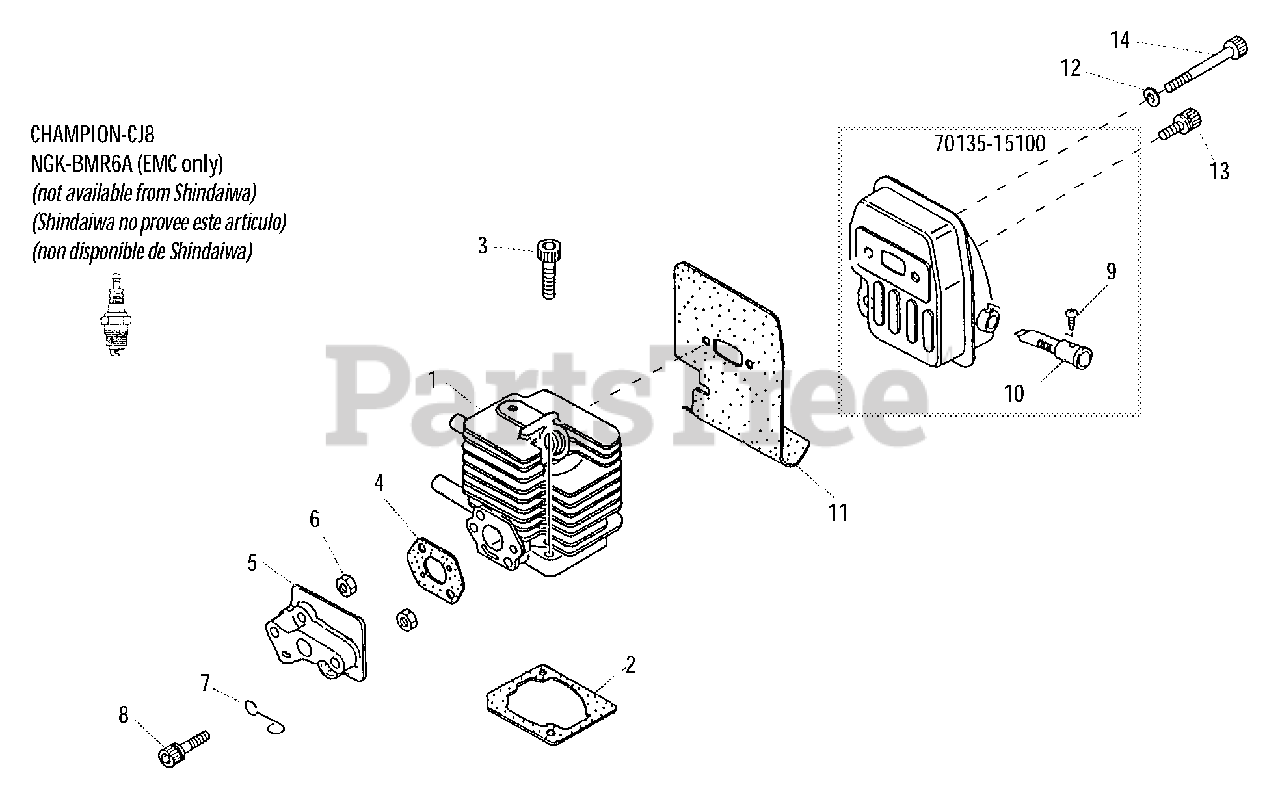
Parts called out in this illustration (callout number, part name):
1	CYLINDER
2	GASKET, CYLINDER
3	SCREW - 5X25
4	GASKET
5	INSULATOR
7	HOLDER, VENT
8	SCREW - 5X30
9	SCREW - 3X6
10	SCREEN, SPARK ARRESTOR
11	SHIELD, EXHAUST
12	WASHER - 5
13	SCREW - 5X12
14	SCREW - 5X50
70135-15100	MUFFLER ASSY
